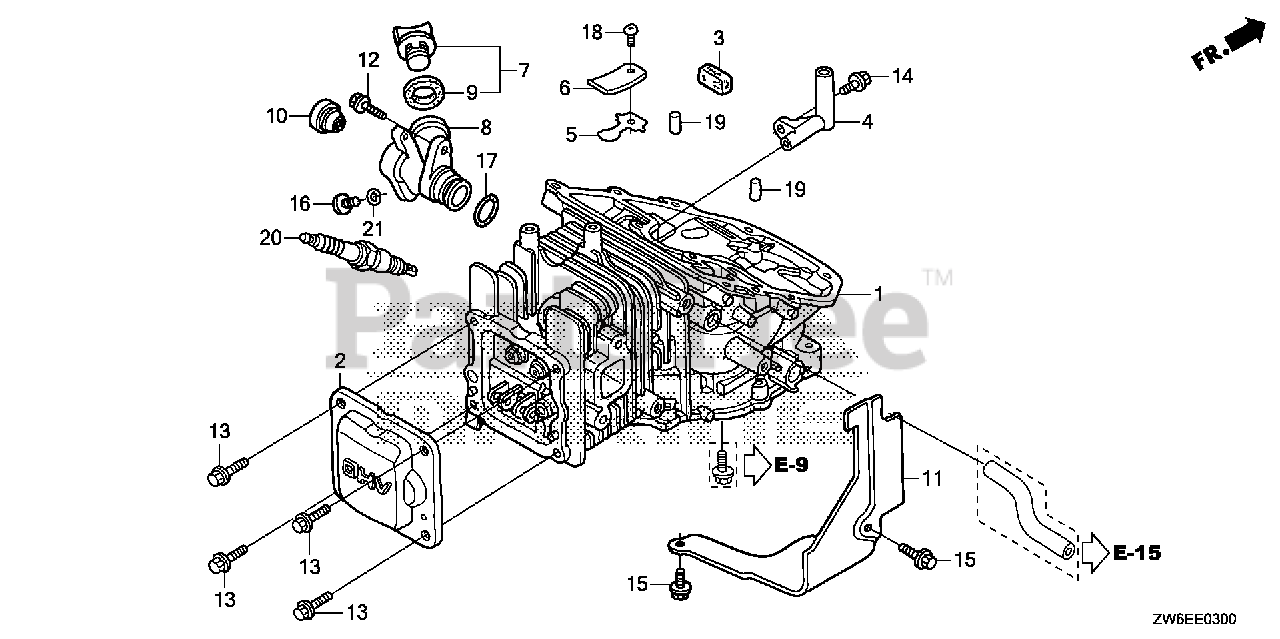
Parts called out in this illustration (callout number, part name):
1	CYLINDER
2	COVER, HEAD *NH105* (MAT BLACK)
3	FILTER, BREATHER
4	PIPE, BREATHER
5	VALVE, OIL OUTLET
6	PLATE, STOPPER
7	CAP ASSY., OIL FILLER
8	EXTENSION, OIL LEVEL FINDER
9	GASKET, OIL FILLER CAP
10	FINDER, OIL LEVEL
11	SHROUD
12	BOLT, FLANGE (5X16)
13	BOLT, FLANGE (5X12)
14	BOLT (4X10)
15	BOLT, FLANGE (5X10) (CT200)
16	BOLT, OIL CHECK
17	O-RING (22.1X2.2)
18	SCREW, PAN (3X5)
19	ROLLER (6X15)
20	SPARK PLUG (U14FSR-UB)
20	SPARK PLUG (CR4HSB)
21	O-RING (6.9X1.5)
